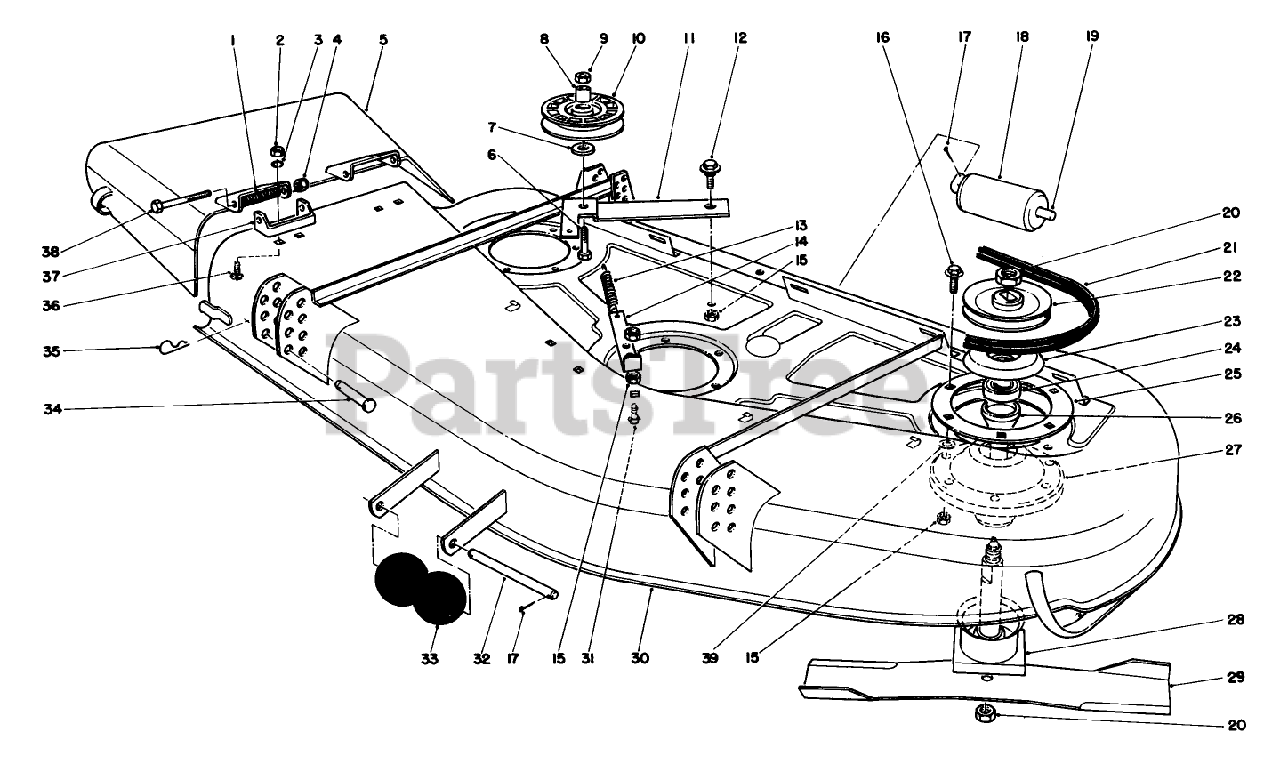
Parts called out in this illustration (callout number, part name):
1	SPRING
2	NUT-HEX
3	WASHER-LOCK
4	NUT-HEX
5	Deflector
6	SCREW-HH
7	Washer
9	NUT-LOCK, NI
10	Pulley-Idler (Incl. Ref. #7 & 8)
11	Lever-Deck
12	SCREW-SHOULDER
13	SPRING-EXTENSION, DECK
14	Anchor-Spring
15	NUT-LOCK, NI
16	SCREW-HHF
17	PIN-COTTER
18	ROLLER-DECK
19	SHAFT-ROLLER, REAR
20	Locknut
21	V-BELT, DECK
22	PULLEY and HUB ASM
23	COVER-DUST
24	BEARING
25	SUPPORT-DECK, RING
26	SPACER-GREASE SHIELD
27	Housing Assembly
28	SHAFT and SADDLE ASM
29	Blade
30	Housing
31	SCREW-CARR
32	SHAFT-ROLLER
33	ROLLER
34	PIN-CLEVIS
35	PIN-HAIR
36	SCREW-CARR
37	Bracket-Pivot
38	SCREW-HH
39	WASHER-FLAT
